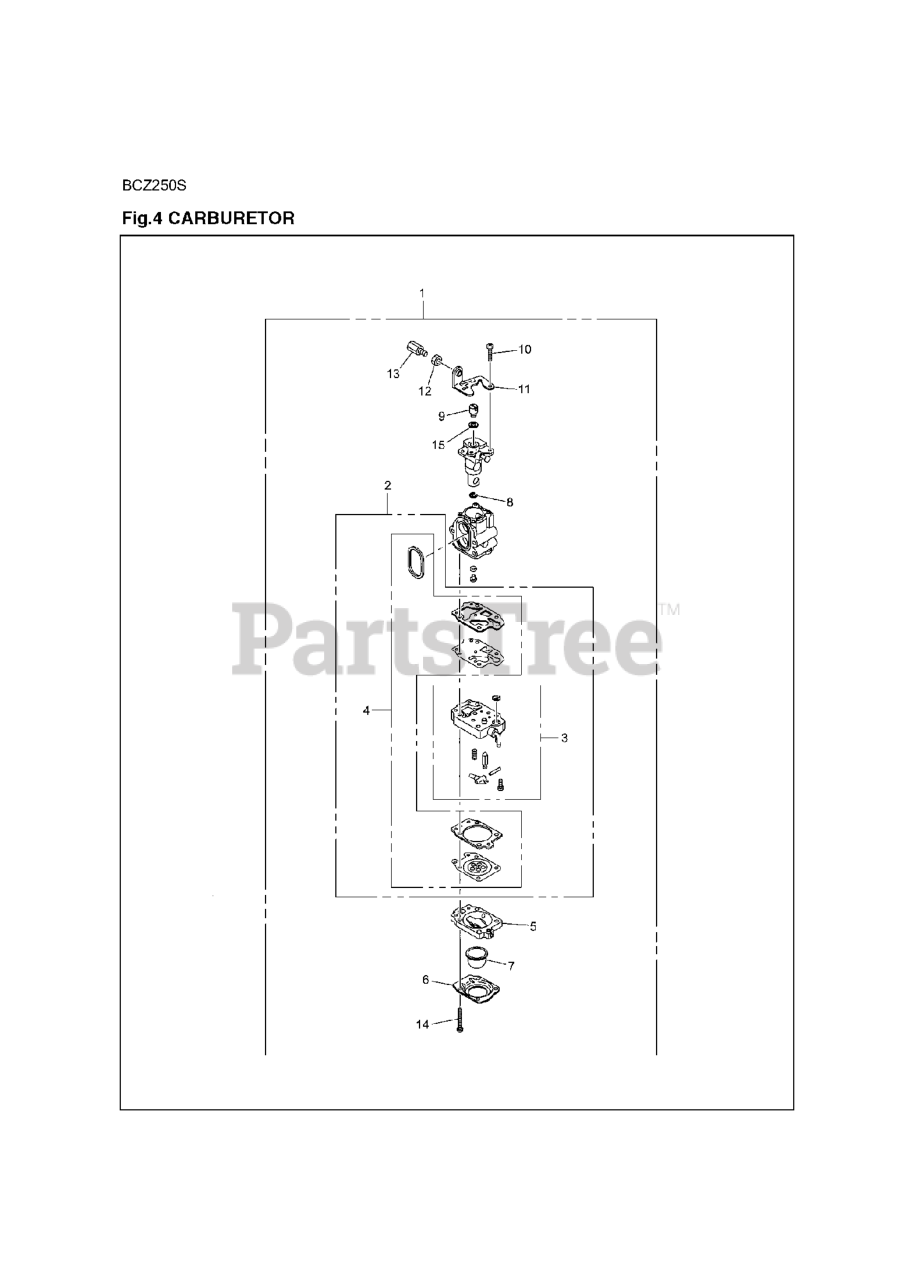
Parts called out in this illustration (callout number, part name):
1	CARBURETOR ASSY
2	REBUILD KIT
3	CARBURETOR BODY
4	GASKET KIT
6	1OVER
8	RING
9	SWIVEL
10	SCREW
11	BRACKET
12	NUT
13	ADJUSTER
15	WASHER
